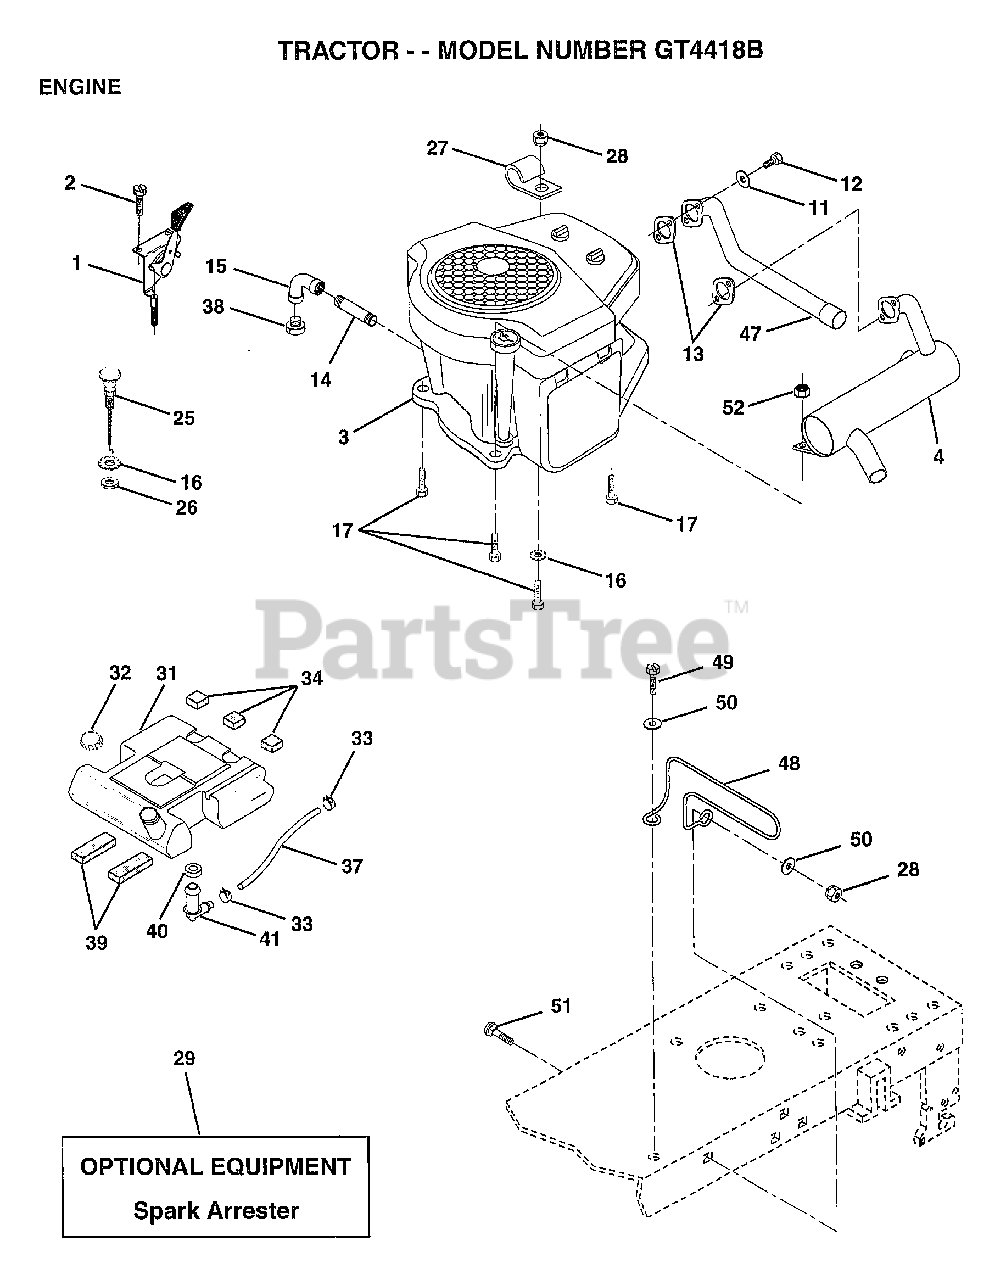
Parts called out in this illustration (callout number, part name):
1	CONTROL.THT.FLG.
2	SCREW LT
11	LOCKWASHER
14	PIPE NIPPLE LT
15	ELBOW
16	LOCKWASHER
17	SCREW LT
25	CHOKE CONTROL
27	"CLIP,INSULATOR"
32	CAP ASM FUEL
33	HOSE CLAMP
34	PAD-SPACER LT
37	FUEL LINE T
39	PAD IDLER TI
40	BUSHING OUTLET T
41	STEM.TANK.FUEL
47	EXHAUST TUBE T
48	MUFFLER GUARD
49	BOLT D
50	WASHER HYT
51	SCREW GTV
